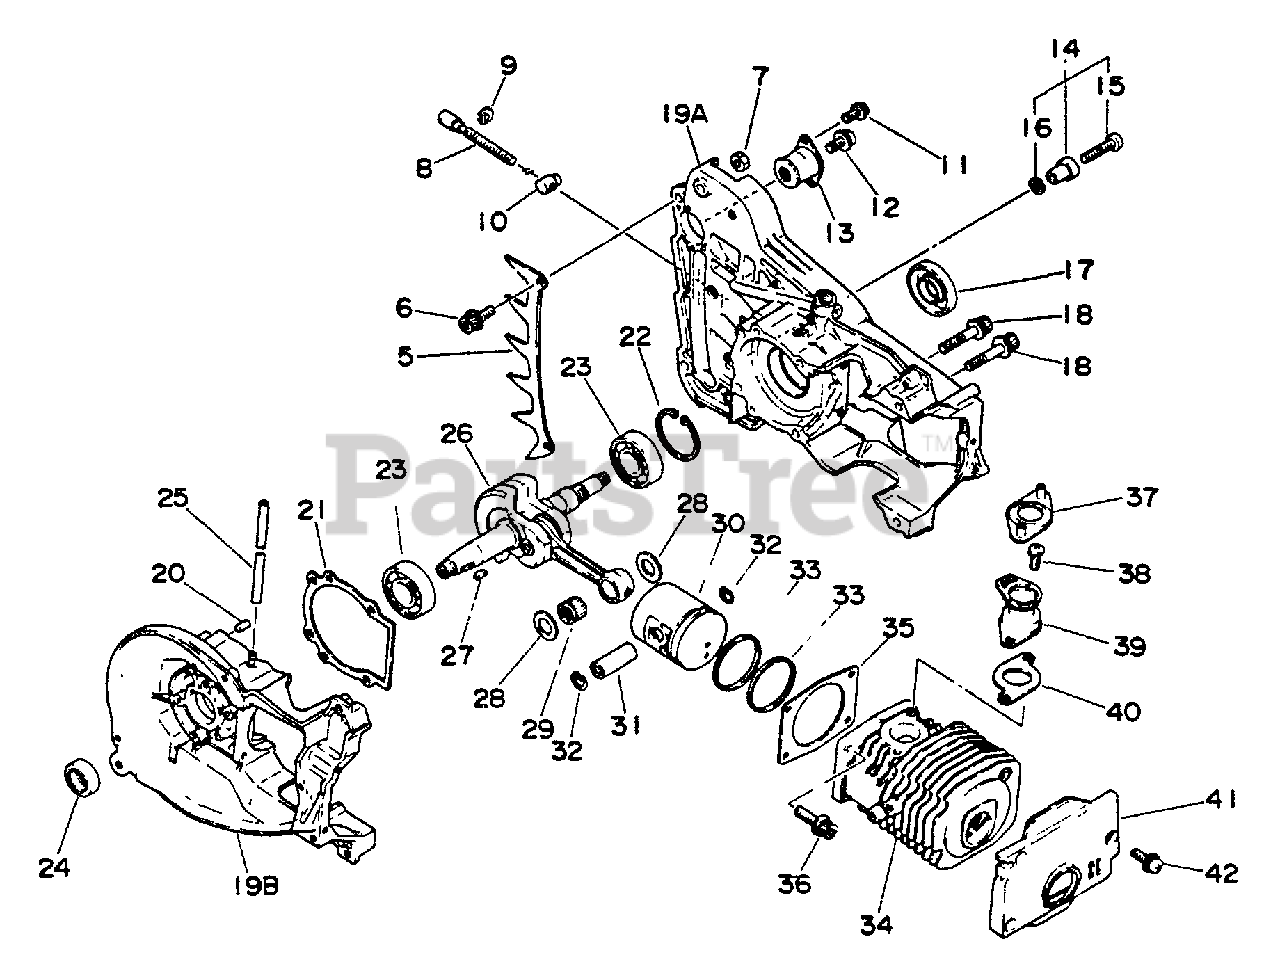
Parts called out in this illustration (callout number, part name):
5	SPIKE
6	SCREW - 5X12
7	LOCKNUT - 5
8	SCREW, TENSIONER
10	TENSIONER, CHAIN
11	SCREW - 4X10
12	SCREW - 5X10
14	CHAIN CATCHER KIT
15	SCREW - 5X25
16	WASHER - 5
17	SEAL, OIL
18	SCREW - 5X30
19	CRANKCASE KIT
19A	CRANKCASE KIT
19B	CRANKCASE KIT
20	PIN - LOCATING
21	GASKET, CRANKCASE
22	RING, RETAINING - 35
23	BEARING, BALL - 6202
24	SEAL, OIL
25	PIPE - 3X6X75 -- BLACK
26	CRANKSHAFT ASSY
28	SPACER, PISTON
29	BEARING, NEEDLE
30	PISTON
31	PIN, PISTON
32	RING, RETAINING - 8
33	RING, PISTON
34	CYLINDER
35	GASKET, CYLINDER
36	SCREW - 5X20
38	SCREW - 5X10
39	ADAPTOR, INTAKE
40	GASKET, INTAKE
41	COVER, CYLINDER
42	SCREW - 4X14
